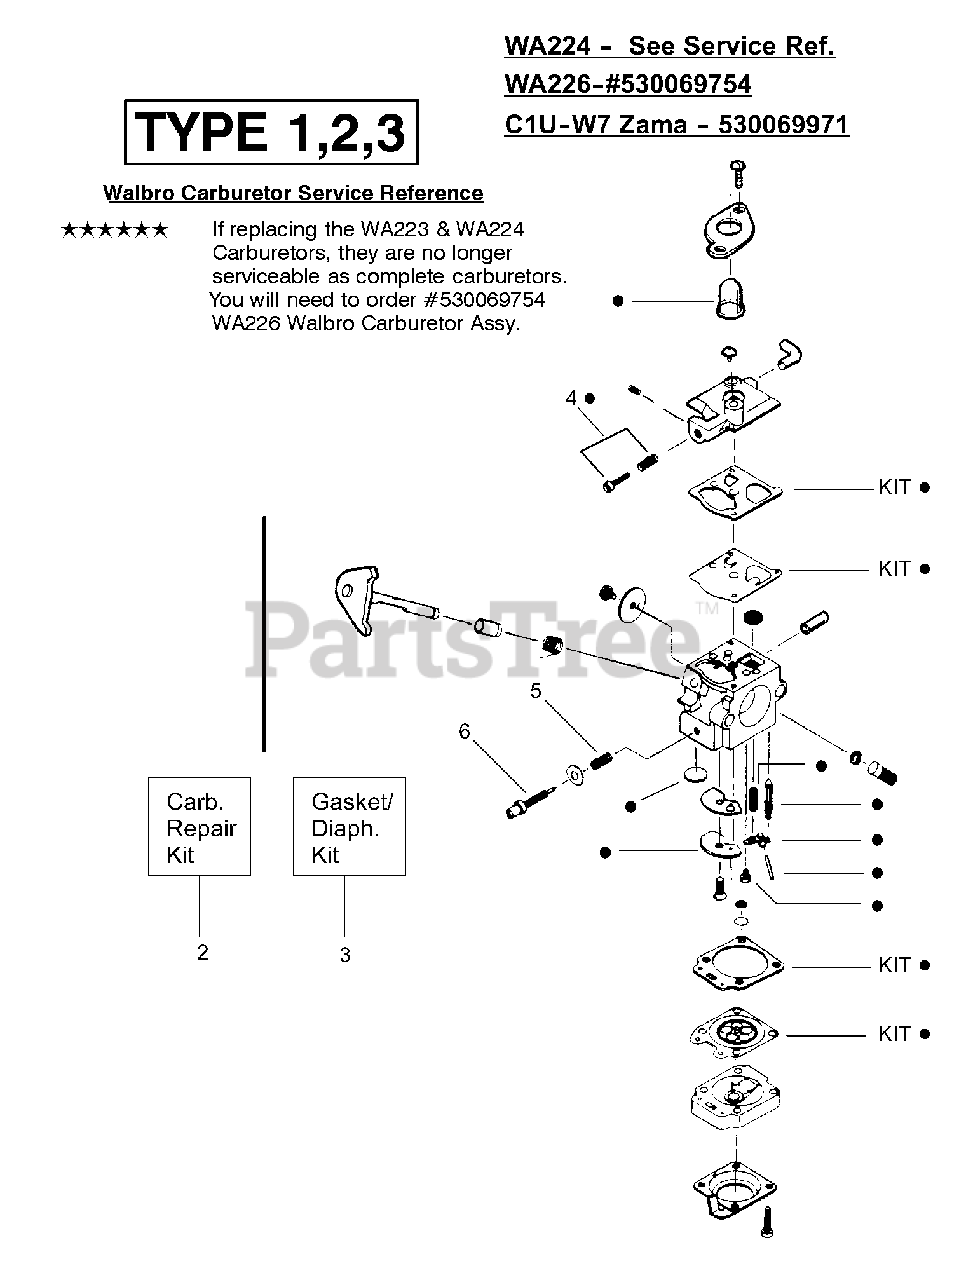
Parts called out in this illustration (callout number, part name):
2	Carburetor Repair Kit WA224
2	Carburetor Repair Kit WA226
2	Carburetor Repair Kit C1U-W7
3	Gasket/Diaphragm WA223, WA224 & WA226
3	Gasket/Diaphragm C1U-W7 (Zama)
4	Idle Screw & Spring Kit
5	Low Speed Spring
6	Low Speed Needle
530069754	Carburetor Assembly - WA226
530069971	Carburetor Assembly - C1U-W7
